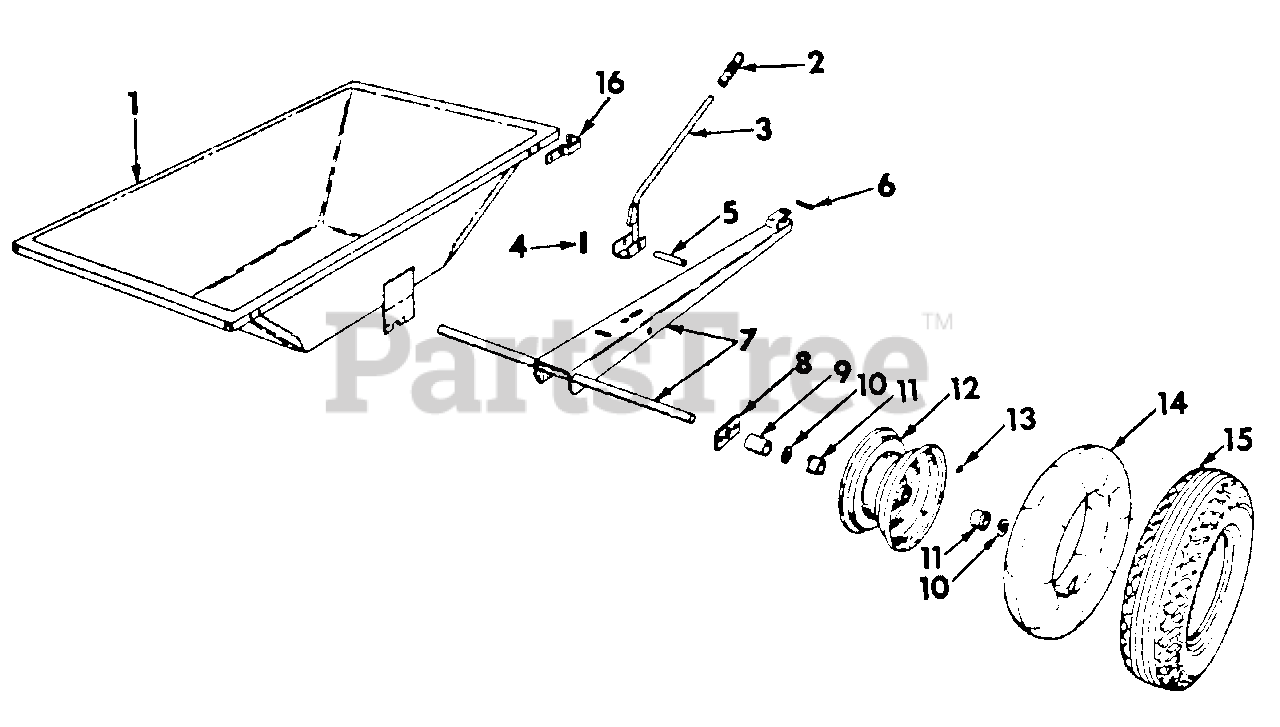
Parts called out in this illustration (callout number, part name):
1	Body Assy, Trailer
2	Grip, Latch Handle
3	Latch Assembly, Dump
4	Spring, Latch
5	Pin, Latch Pivot
6	Pin, Quick Attachable Cot
7	Chassis Assembly, Body
8	Retainer, Axle
9	Spacer, Wheel
11	Bearing, Wheel
12	Wheel Assy -Will work for 376 187 R91
13	Fitting, 1/4-28 Str Lub
15	Tire, Pneumatic -4.80/4.00 X 8- -Rim tread
16	Parts Accessory, Stake Pocket
